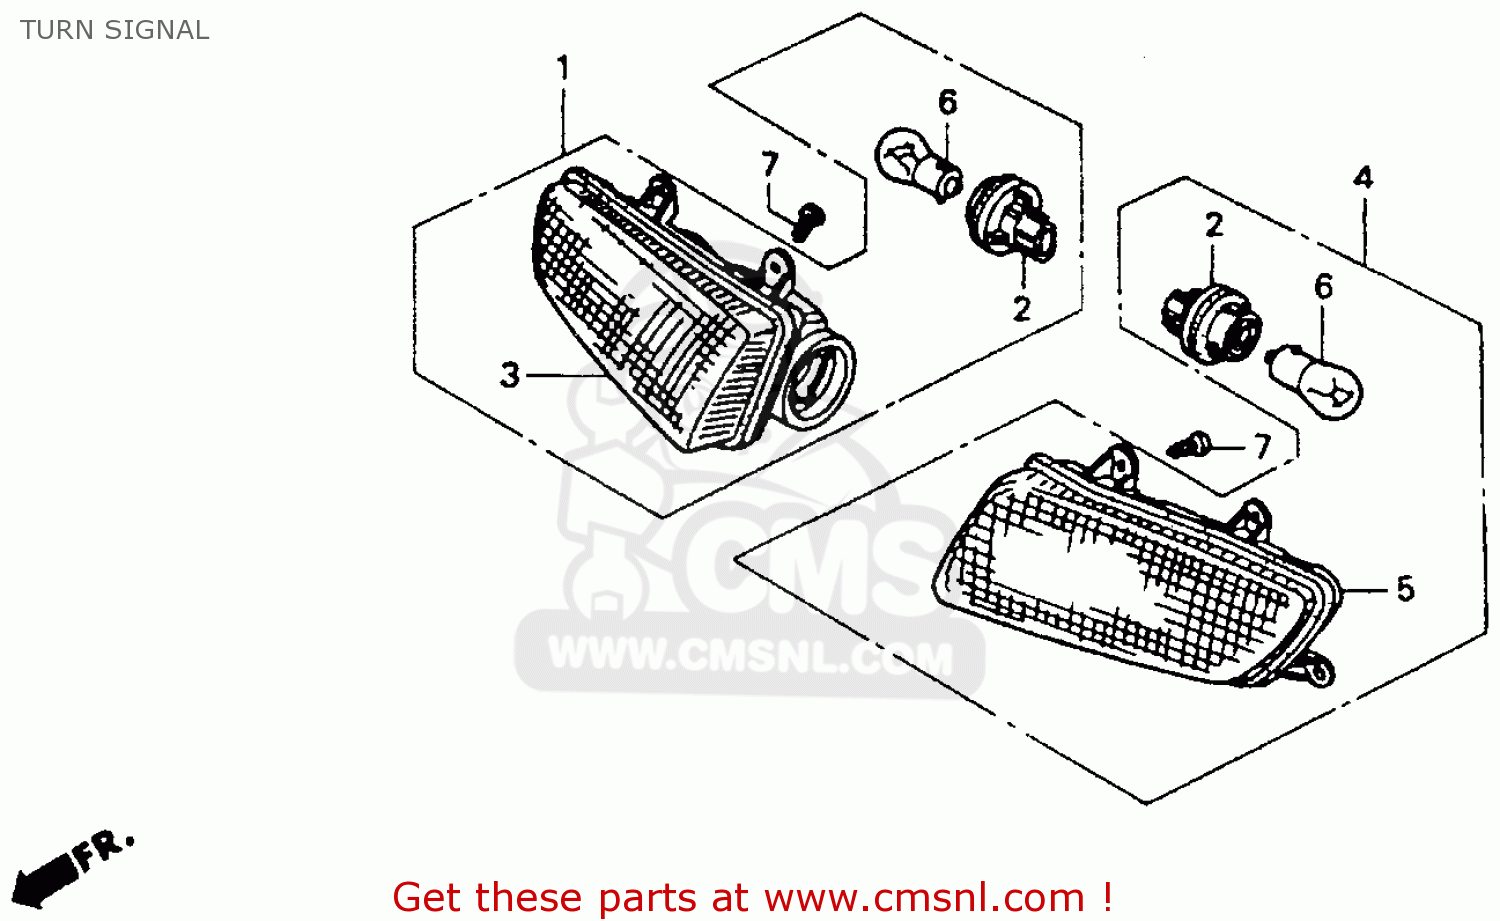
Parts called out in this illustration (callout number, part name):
1	WINKER ASSY.,R.FR
2	SOCKET,BULB (3P)
3	SUB ASSY.,R,FR.WI
4	WINKER ASSY.,L.FR
5	SUB ASSY.,L,FR WI
6	BULB,WINKER
7	SCREW TAPP 4X16
